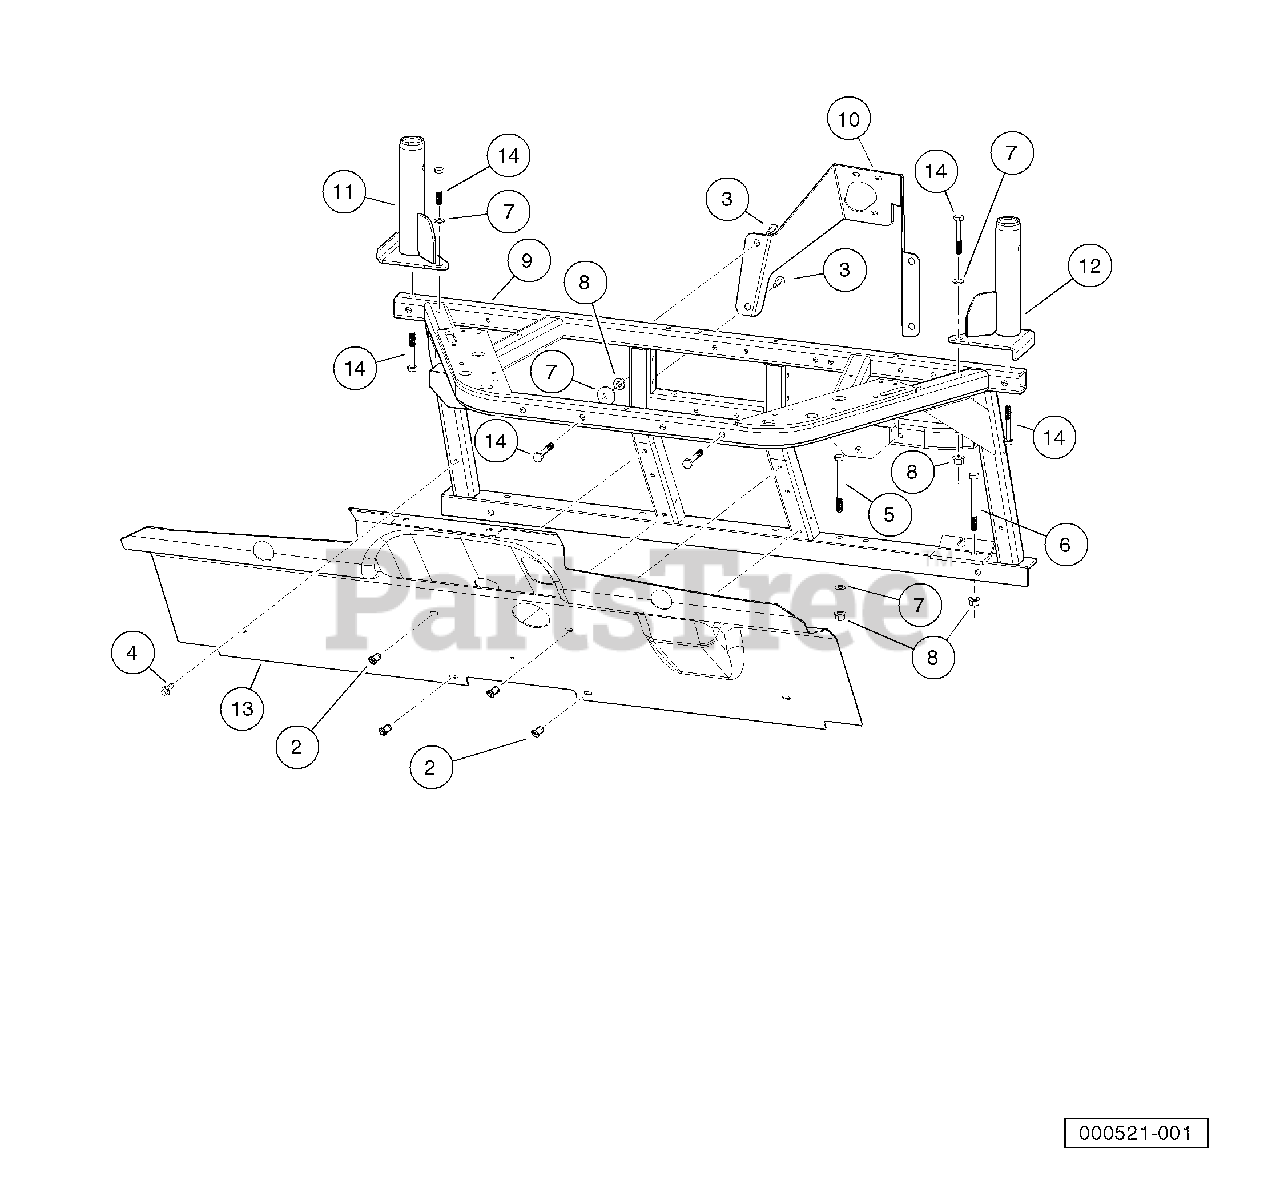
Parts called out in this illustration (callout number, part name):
1	Instl, Cowl Weldmnt/Splash Guard
2	Blind Rivet, Push Type
3	Nut,m8,all Metal Lock
4	M8-1.25x20 Taptite
5	Washer, Flat, 3/8, Blk Fin
6	Bolt, M10x1.50x100
7	Bolt, M10 X 1.50 X 110 Black
8	Washer Hard,m10
9	Nut Flg M10 X 15 Mech Def
10	Bolt Flanged Head, M8 X 1.25 X 65
11	Weldment, Dash, Front
12	Bracket, Column, Steering
13	Weldment, Front, Base, ROPS, Right-Hand
14	Weldment, Front, Base, ROPS, Left-Hand
15	Guard, Splash, Gas Injection
16	Bolt, M10 X 1.50 X 65
